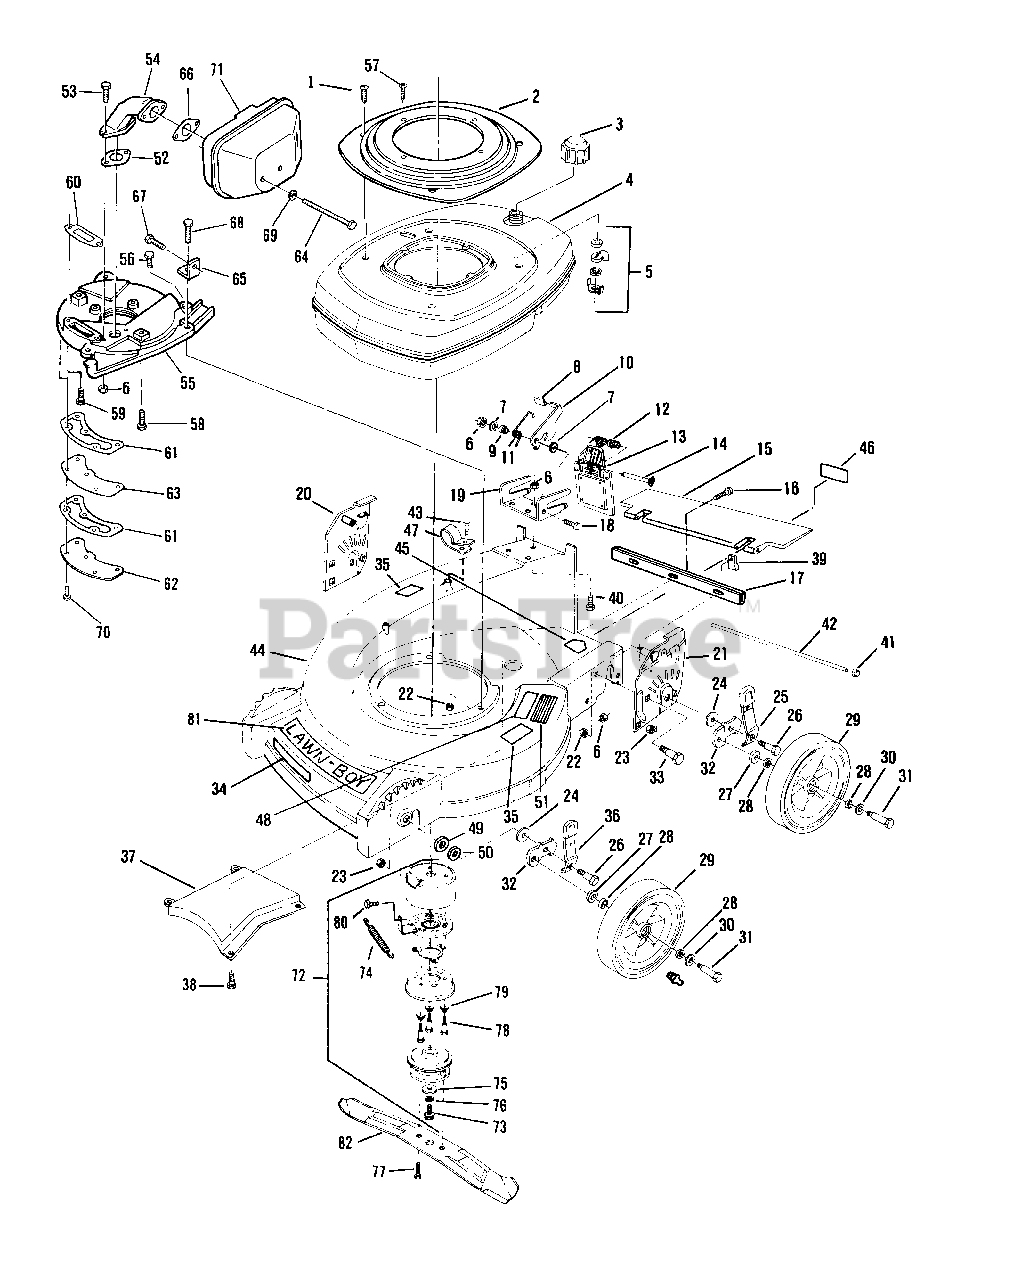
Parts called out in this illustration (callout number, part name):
1	Screw
2	Cover-Shroud
3	Fuel Cap
4	Shroud-Engine
5	Fuel Shut-Off Assembly
6	Nut-Latch Brkt., Trailing Shield and Muffler to Exh. Pipe
7	Washer-Latch Spacer and Latch Spring
8	Knob-Latch
9	Stepped Spacer
10	Latch-Bag
11	Spring Latch
12	Spring
13	Door
14	Rod
15	Shield-Trailing
16	Screw-Latch Bracket and Trailing Shield
17	Bracket-Bag Hanger
18	Screw-Latch to Bracket
19	Hinge Plate
20	Bracket-Handle-R.H.
21	Bracket-Handle-L.H.
22	Nut-Handle Bracket and Muffler Plate to Housing
23	Nut-Wheel Ht. Adjust.
24	Washer-Wheel Ht. Adjust
25	Knob and Spring Assembly
26	Bolt-Shoulder
27	Washer
28	Washer-Felt
29	Wheel and Tire Assembly
30	Washer-Wheel Bolt
31	Bolt-Shoulder-Wheel
32	Bracket-Wheel-Ht. Adjust
33	Bolt-Handle Bracket Mounting
34	Decal-Headliner
35	Decal-Height Adjust
36	Knob and Spring Assembly
37	Baffle
38	Screw-Baffle to Housing
39	Clamp-Rod
40	Screw-Truss Head
41	Nut-Rod
42	Rod-Trailing Shield
43	Screw-Clamp to Housing
44	Housing Assembly
45	Decal-Blade Contact Warning
46	Decal-Caution
47	Clamp-Cable and Primer to Housing
48	Decal-Starting Pad
49	Washer-Shim-Whl Ht. Adj. Brk't.
50	Washer-Shim-Whl Ht. Adj. Brk't.
51	Pad-Starting
52	Gasket-Exh. Pipe to Mtg. Plate
53	Screw-Exh. Pipe to Mtg. Plate
54	Exhaust Pipe Assembly
55	Mounting Plate
56	Bolt
57	Screw-Starter Mount
58	Screw-Muffler Plate to Block
59	Screw-Muffler Plate Block
60	Gasket-Exhaust
61	Gasket-Muffler
62	Cover Gasket
63	Baffle
64	Screw
65	Bracket-Muffler
66	Gasket-Muffler
67	Screw
68	Bolt
69	Washer
70	Screw-Locking
71	Muffler
72	Clutch Assembly
73	Screw
74	Spring
75	Washer
76	Lockwasher
77	Screw
78	Screw
79	Spring
80	Bolt-Shoulder-Clutch Arm
81	Decal-Lawn-Boy
82	Blade 20"
